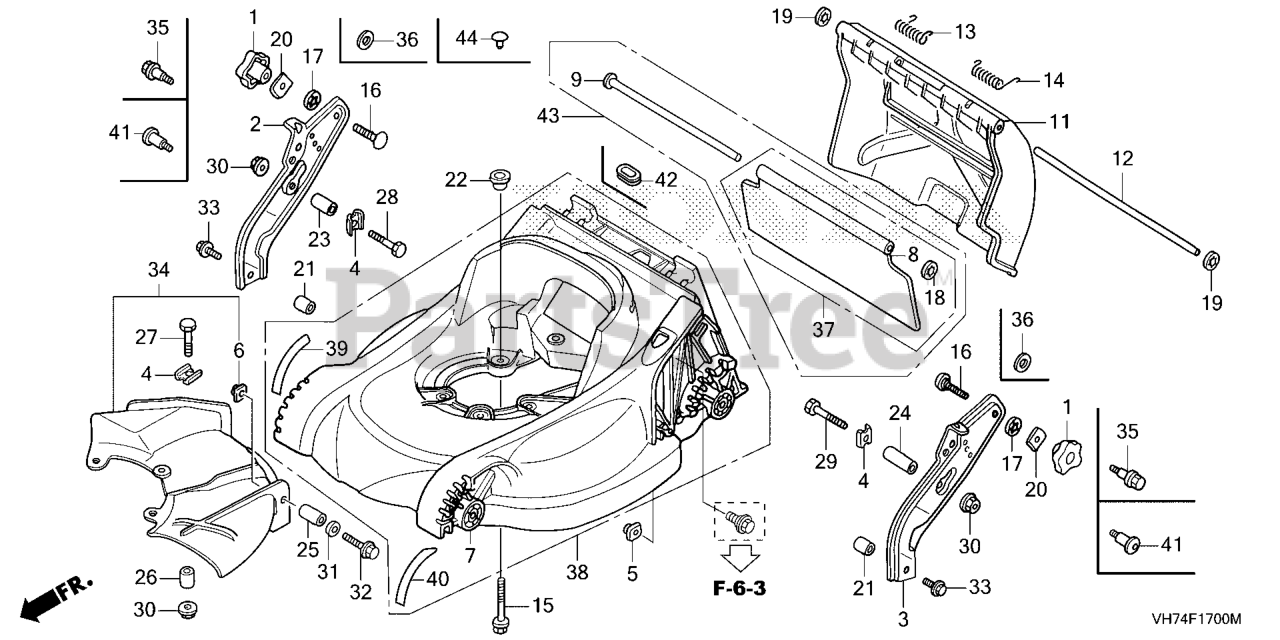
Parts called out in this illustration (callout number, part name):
2	STAY, R. HANDLE *NH105* (MAT BLACK)
3	STAY, L. HANDLE *NH105* (MAT BLACK)
4	HOLDER, HANDLE STAY
5	NUT, HEADLIGHT SETTING
6	NUT, SPECIAL (6X7)
7	HOUSING, CUTTER *NH462R* (VINTAGE GRAY SOLID)
8	SHIELD, RR.
9	SHAFT, RR. SHIELD
11	GUARD, DISCHARGE
12	SHAFT, DISCHARGE GUARD
13	SPRING, R. GUARD RETURN
14	SPRING, L. GUARD RETURN
15	BOLT, ENGINE SETTING
18	NUT, PUSH (3.96MM) (FLAT ROUND TYPE)
19	NUT, PUSH (7.94MM)
21	COLLAR, STAY (LOWER)
22	COLLAR, BED
23	COLLAR, R. STAY (UPPER)
24	COLLAR, L. STAY (UPPER)
25	COLLAR, SCROLL
26	COLLAR, SCROLL
27	BOLT, HEX. (8X28)
27	BOLT, HEX. (8X30)
28	BOLT, HEX. (8X40)
29	BOLT, HEX. (8X50)
30	NUT, FLANGE (8MM)
31	WASHER, PLAIN (6MM)
32	BOLT, FLANGE (6X35)
33	BOLT, FLANGE (8X22) Use from Engine SN 1609607.
34	GUIDE ASSY., SCROLL
36	WASHER (25MM)
39	MARK, R. FR. HEIGHT INDICATION
40	MARK, FR. L HEIGHT INDICATION
41	BOLT, SPECIAL (8X32)
